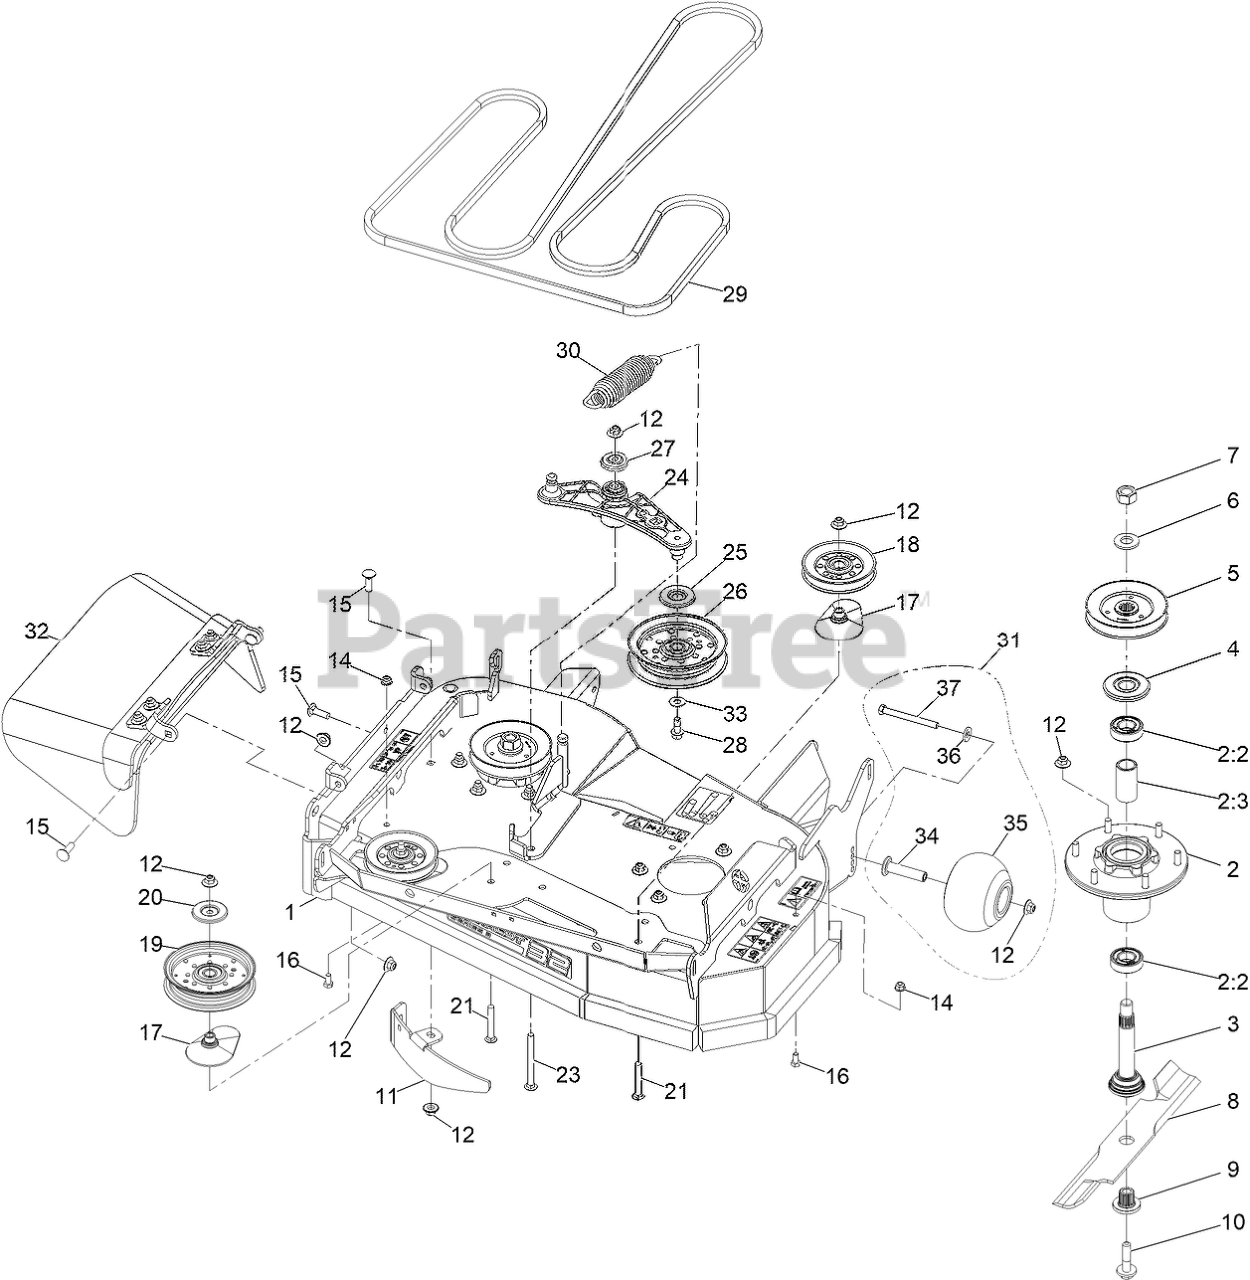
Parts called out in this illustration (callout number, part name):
1	ASM-DECK DECALS 32
2	ASM-CUTTER HSG WITH BEARINGS
2:2	BEARING-BALL
2:3	SPACER-BEARING
3	ASM-SPINDLE AND SEAL
4	GUARD,BEARING TOP .989
5	SHEAVE-BLADE DRIVE
7	NUT-HEX
9	BUSHING,SPLINED
10	SCREW,SEMS 1/2-20 X 2.19
11	BAFFLE, DOGLEG
12	Nut-Nyloc 3/8-16 Flg
14	NUT-HF, NI
15	BOLT-CARR
16	SCREW-HH
17	SPACER-PULLEY
18	Idler - V 4.13 Eod-A
19	PULLEY-IDLER, FLAT
20	SHIELD-DUST
21	SCREW-CARR
23	SCREW-CARR
24	ASM.-ARM, IDLER
25	SHIELD-GUARD, DUST
26	IDLER-PULLEY, FLAT
27	GUARD-TOP
28	SCREW-HFH
30	SPRING-EXTENSION
31	KIT, ANTI-SCALP ROLLER
32	RUBBER DEFLECTOR ASM
33	WASHER-FLAT
34	AXLE, ROLLER
35	ROLLER-SCALP, ANTI
36	WASHER-BELLEVILLE
37	SCREW-HH 3/8-16 X 3 3/4 GR 8
